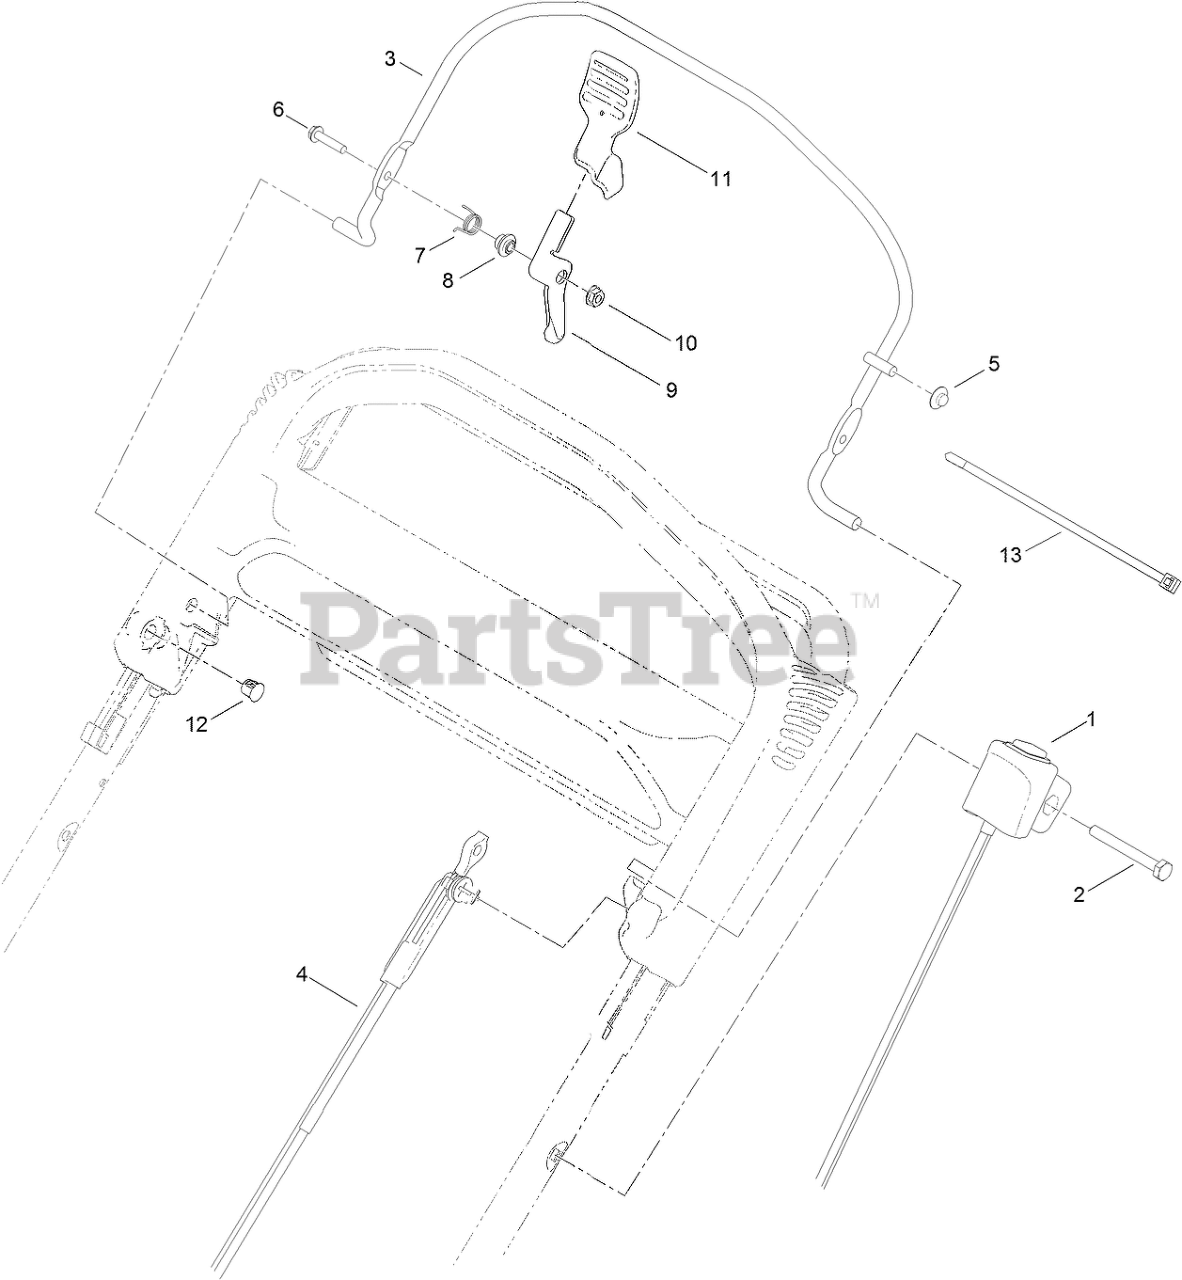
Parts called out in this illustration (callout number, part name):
1	SWITCH HOUSING ASM
2	SCREW-HH
3	BAIL-BRAKE
4	CABLE-BRAKE
5	NUT-SPEED
6	SCREW-HWH
7	SPRING-TORSION
8	SPACER
9	LEVER
10	NUT-LOCK, FLANGE
12	Plug-Dome
13	TIE-CABLE
